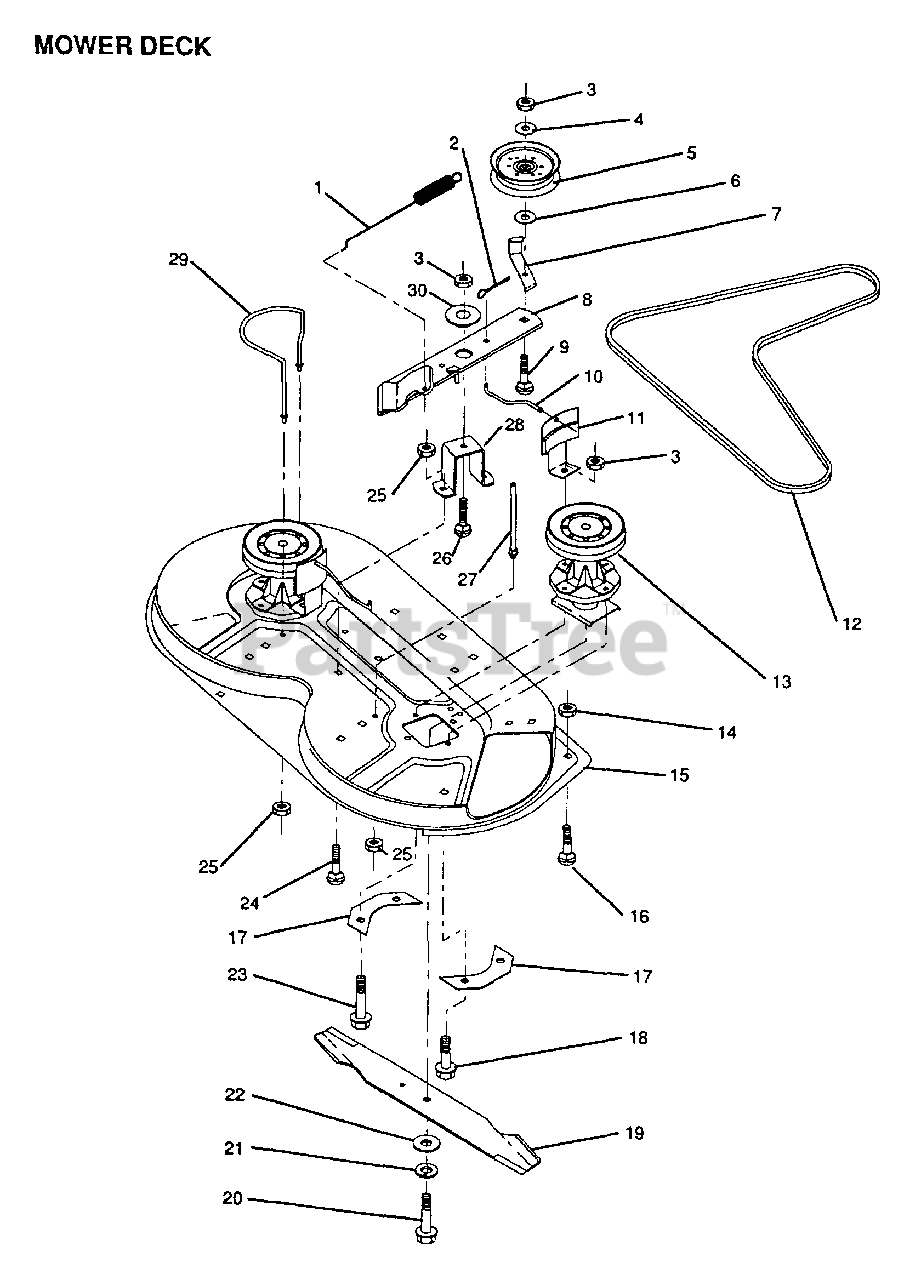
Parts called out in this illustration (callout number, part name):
4	WASHER
5	PULLEY IDLER
6	WASHER GT
8	IDLER ARM ASS'Y
9	BOLT CARRIAGE
10	ROD BRAKE
11	BRAKE LT
12	BELT.MOWER.79.75
13	MANDREL ASS'Y
16	BOLT
17	SUPPORT PLATE LT
18	SCREW
19	"BLADE.36""HIGH LIF"
20	BOLT.3/8-24X1-1/2
22	WASHER
23	SCREW
24	BOLT
26	BOLT D
27	"GUIDE,REAR BEL RH"
28	"SUPT,IDLER ARM"
29	GUIDE BELT LH
30	SPACER RETAINER
